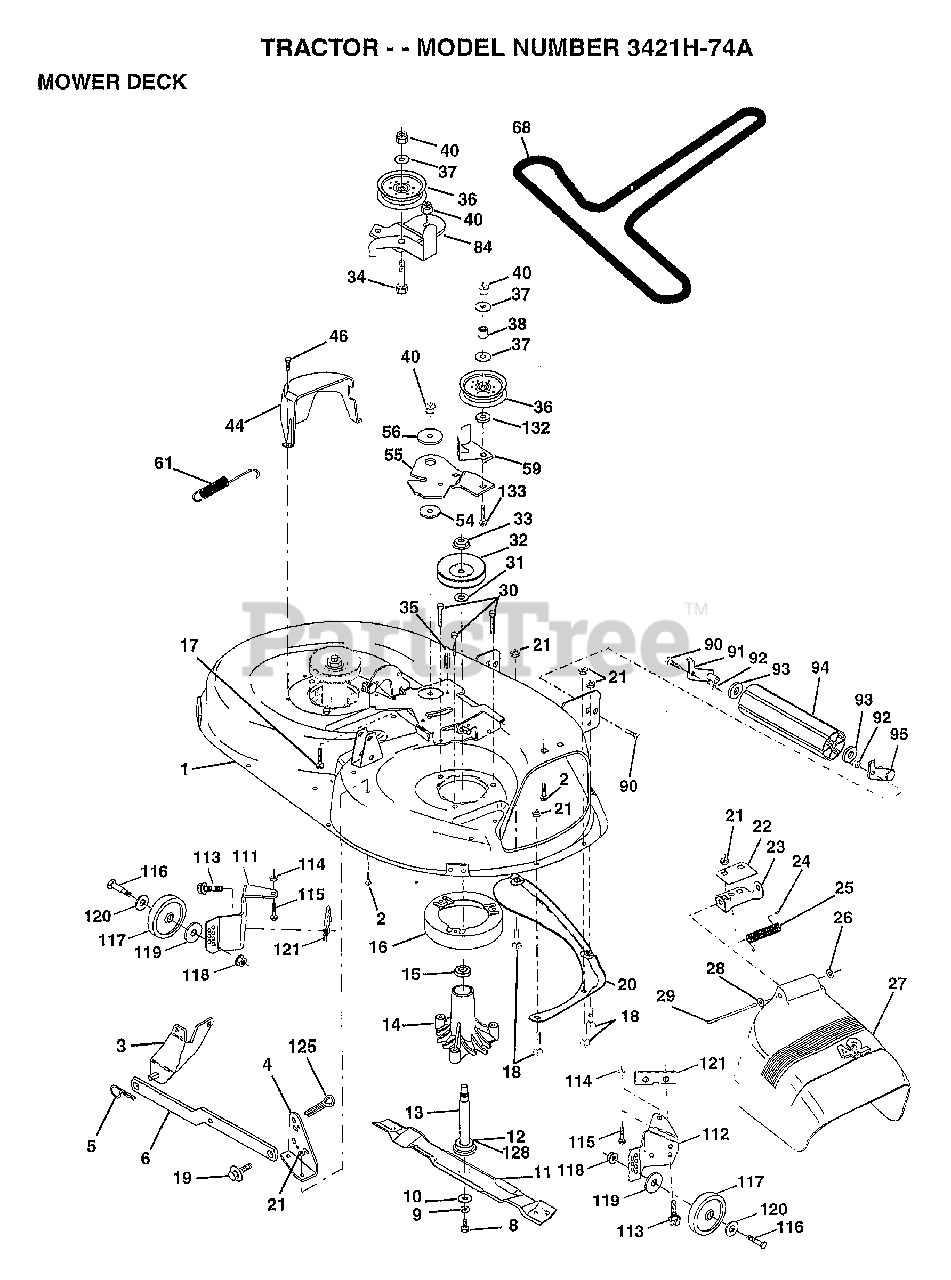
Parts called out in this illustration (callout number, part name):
1	DECK.WELD.42.
2	BOLT
3	BRKT ASM SWAY BAR
4	BRKT DECK SW BAR
8	BLADE BOLT
10	WASHER.HARD.BLADE
11	"BLADE.42"" HIPERF"
12	BEARING.BALL
14	HSG ASM MANDREL
15	BEARING
16	STRIPPER RND MWR
17	BOLT CARRIAGE
18	BOLT
19	BOLT SHD 5/16-18
22	STIFFENER BRKT
23	DEFLECTOR BRKT
24	CAP-SLEEVE LT
25	SPRING TORSION
26	NUT PUSH M
27	DEFLECTOR.SHIELD
28	WASHER
29	HINGE ROD
31	WASHER
32	PULLEY.MANDREL.42
34	BOLT
35	XMAS TREE FASTNER
36	FLAT IDLER PULLEY
37	WASHER
44	GUARD MAND LH BLK
46	SCREW.1/4-20X5/8
54	HARDENED WASHER
56	SPACER RETAINER
59	GUARD IDLER TUV
61	SPRING.EXTENSION
68	BELT-V.SEC.46.KEL
84	BRACKET ASM IDLER
90	BOLT
92	NUT
93	WASHER
111	BRACKET.GWHL.LH.
112	BRACKET.GWHL.RH.
113	SCREW
116	BOLT M
117	WHEEL.GAGE.BLK.PL
118	LOCKNUT
119	WASHER
120	WASHER
121	BRACKET.EXTRD.GWL
128	WASHER.FELT.
132	WASHER GT
133	BOLT
